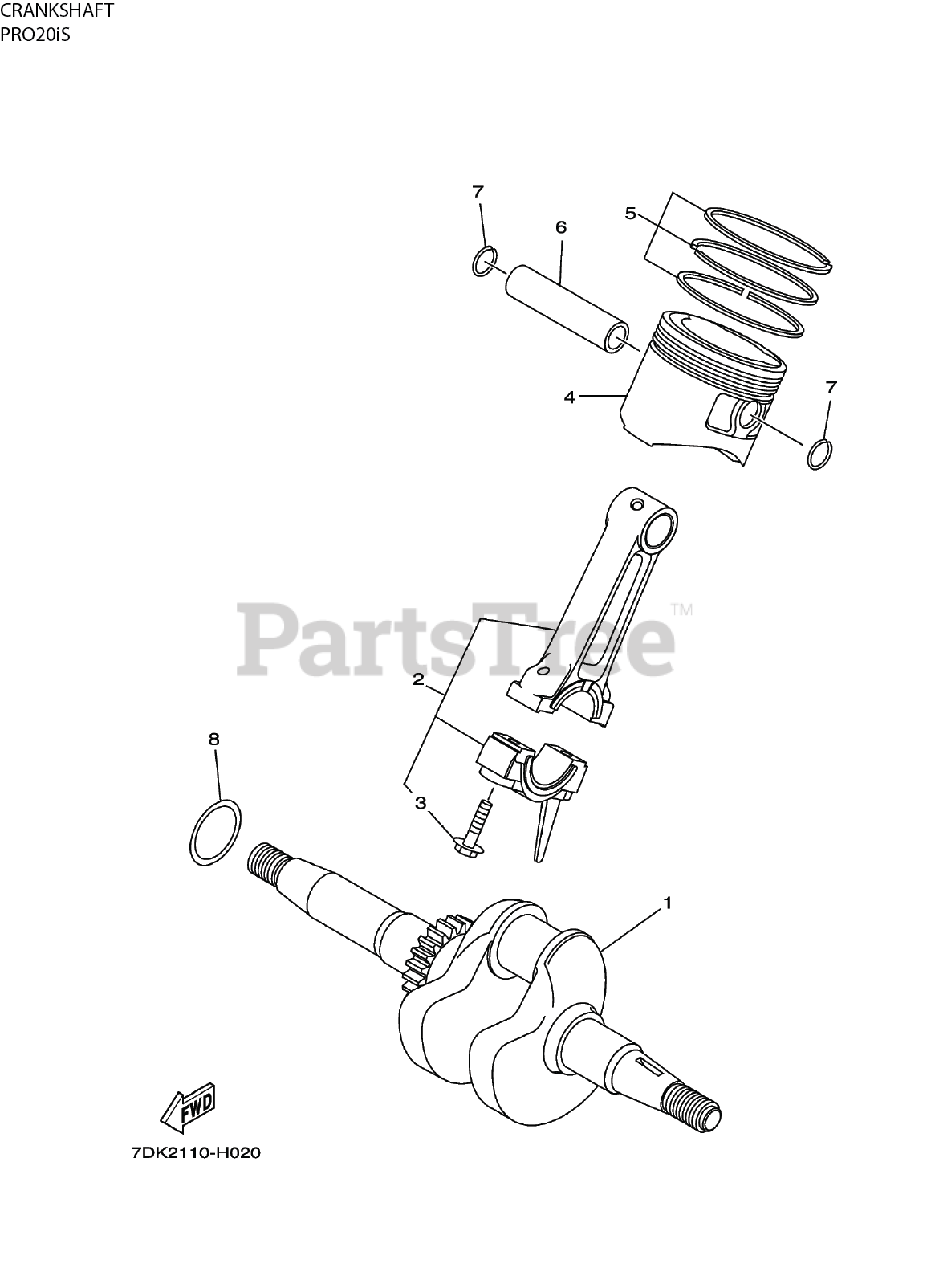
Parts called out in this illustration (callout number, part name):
1	CRANKSHAFT ASSEMBLY
2	ROD ASSEMBLY, CONNECTING
3	SCREW - BOLT CONNECTING ROD
4	PISTON (STD)
4	PISTON (0.25MM O/S)
4	PISTON (0.50MM O/S)
5	PISTON RING SET
6	PIN, PISTON
7	RETAINER, CIRCLIP
8	SHIM, CRANK 1
